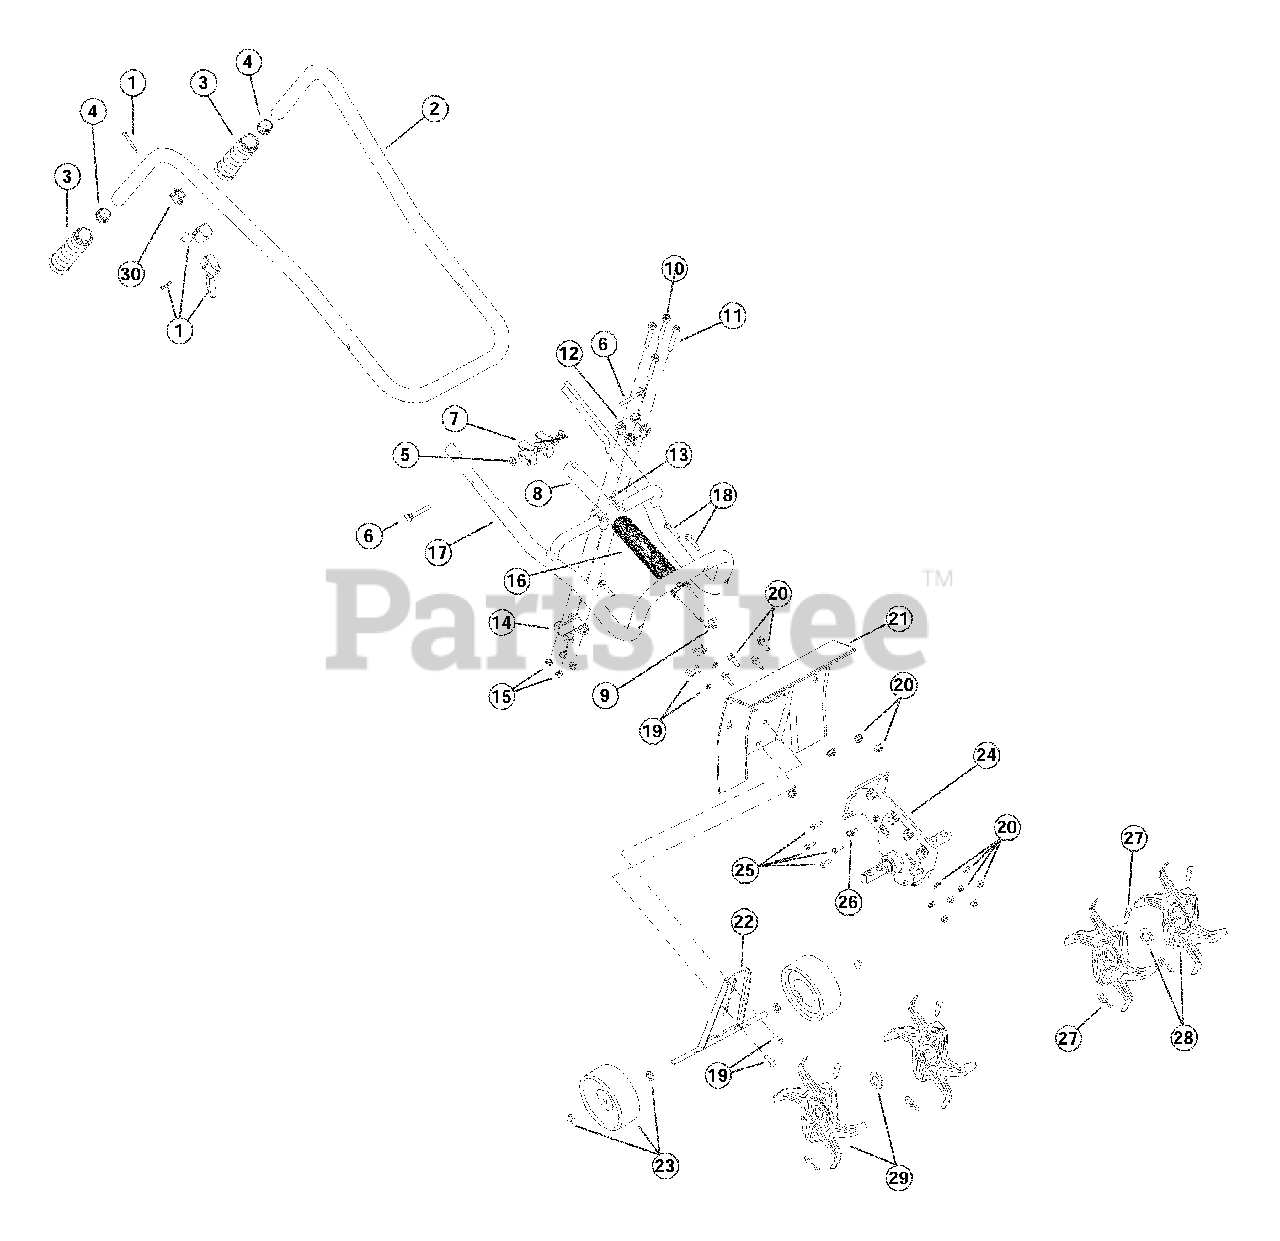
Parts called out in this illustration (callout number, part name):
1	Throttle Trigger and Cable Assembly
2	Handle Bar Assembly, Upper
4	Tube Closure
5	Washer
7	Knob, 3 prong
8	Drive Shaft Housing Assembly
9	Flexible Drive Shaft
10	Handle Bracket Assembly
12	Handle Clamp
13	Handle Clamp
14	Handle Clamp
17	Lower Handle Bar
18	Hardware, Handle Bar Mounting (lower)
19	Wheel Bracket Mounting Hardware
20	Guard Mounting Hardware
22	Wheel Bracket Assembly
23	Wheel Assembly
24	Gear Box Assembly
26	Sleeve Retainer Bolt
27	Tine Fastener Assembly
28	Tine Assembly (Left Outer or Right Inner)
29	Tine Assembly (Left Inner or Right Outer)
